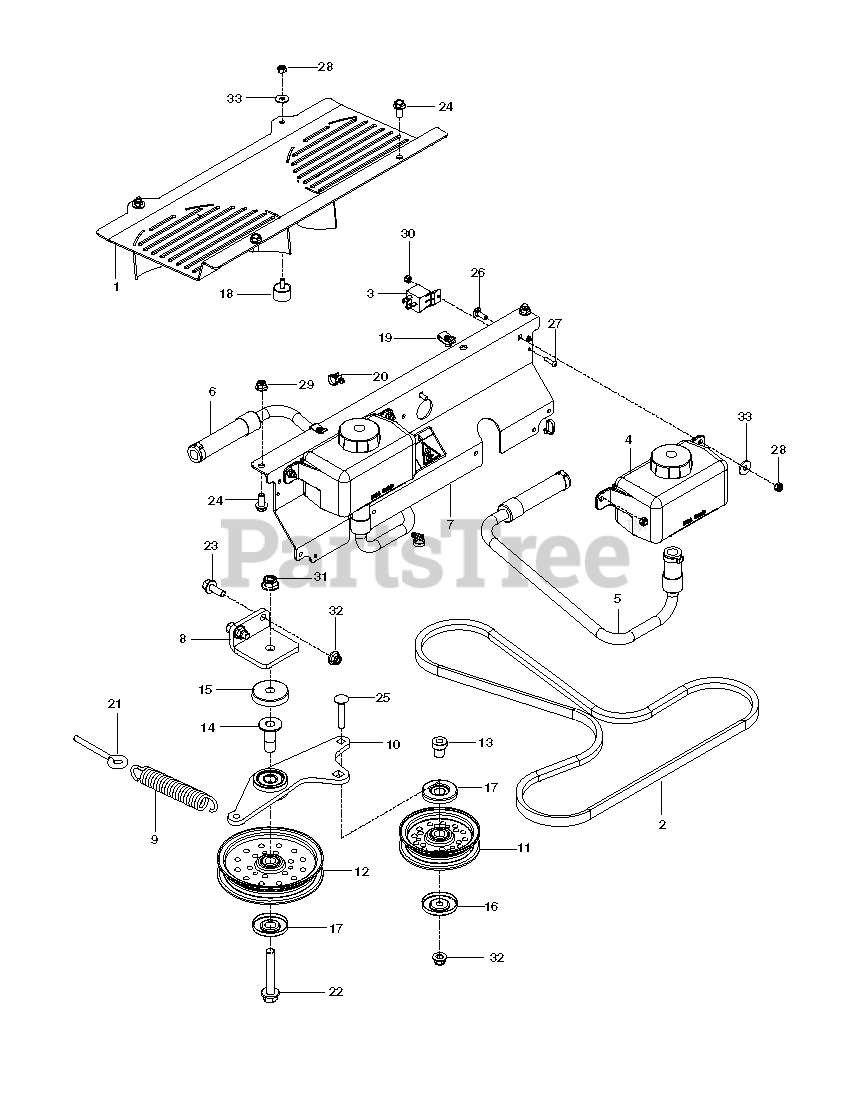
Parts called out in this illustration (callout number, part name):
11	IDLER PULLEY
12	IDLER, FLAT, 5.5"
13	PIVOT, IDLER
15	SHIELD, DUST
16	DUST SHIELD
17	SHIELD, DUST
18	BUMPER, MALE STUD, 1/4-20
19	U-CLIP 5/16-18 NUT RETAINER
21	EYE BOLT 5/16 X 3.50
22	HFFS 1/2-13 X 3 GD 5 ZD
23	HHFS 3/8-16 X 1 GRD 5 ZD
24	HHFS 5/16-18 X 3/4
25	RHSNB 3/8C X 2
26	RHSNB 1/4C X 3/4
27	SCR #10-24 X .75 SKT HD BLK
28	NUT 1/4-20 NYLOC
29	5/16-18 NYLOC FLANGE NUT
30	NUT 10-24 NYLOC
31	NUT, 1/2-13 HEX FLG NYLOC ZD
32	NUT 3/8-16 HEX FLG NYLOC ZD
33	WASHER 1/4 FLAT
